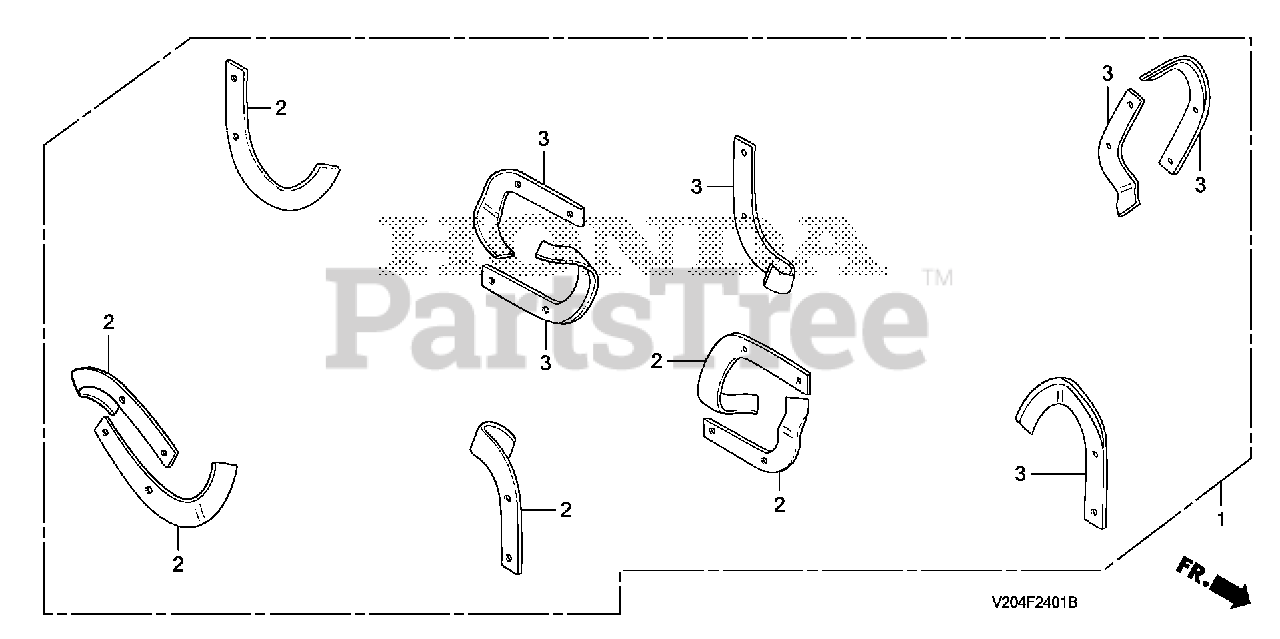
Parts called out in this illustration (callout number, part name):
1	TINE KIT, ROTARY
2	TINE A, ROTARY
3	TINE B, ROTARY
